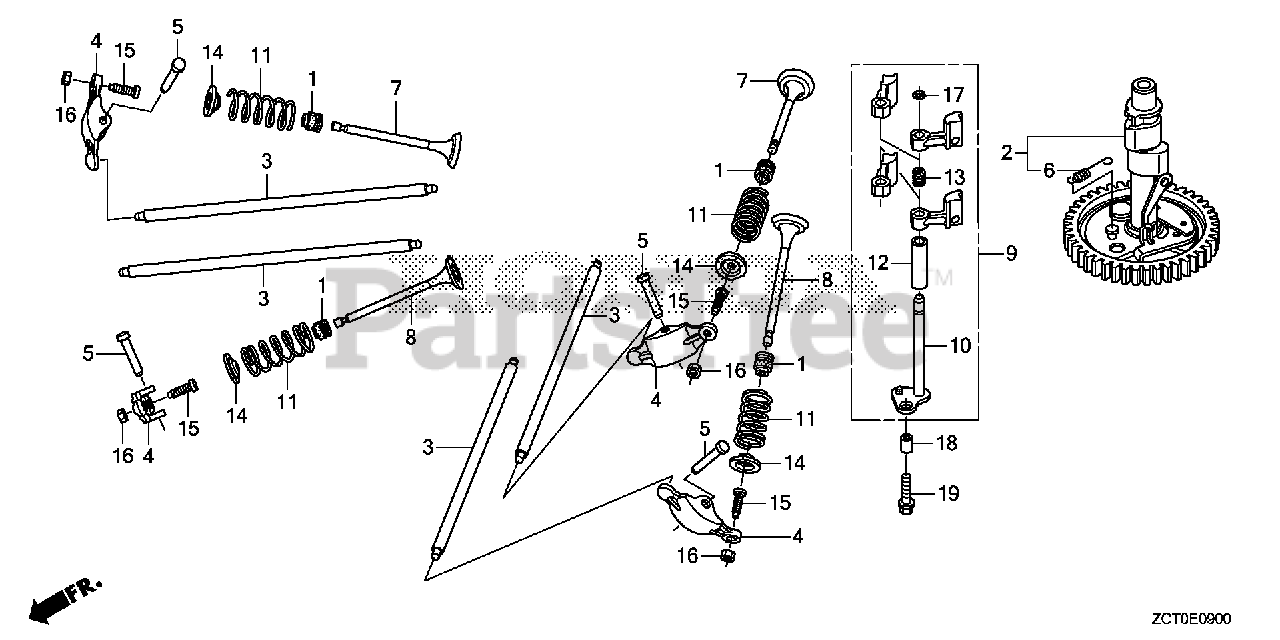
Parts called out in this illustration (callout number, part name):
1	SEAL, VALVE STEM
2	CAMSHAFT ASSY.
4	ARM, VALVE ROCKER
5	SHAFT, ROCKER ARM
6	SPRING, WEIGHT RETURN
7	VALVE, IN.
8	VALVE, EX.
9	LIFTER ASSY., VALVE
10	SHAFT, VALVE LIFTER
11	SPRING, VALVE
12	COLLAR, VALVE LIFTER
13	SPRING, VALVE LIFTER
14	RETAINER, IN. VALVE SPRING (IN./EX.)
14	RETAINER, VALVE SPRING
15	SCREW, TAPPET ADJUSTING
16	NUT, TAPPET ADJUSTING
17	CLIP, GOVERNOR HOLDER
18	PIN, DOWEL (8X10)
19	BOLT, FLANGE (6X22)
